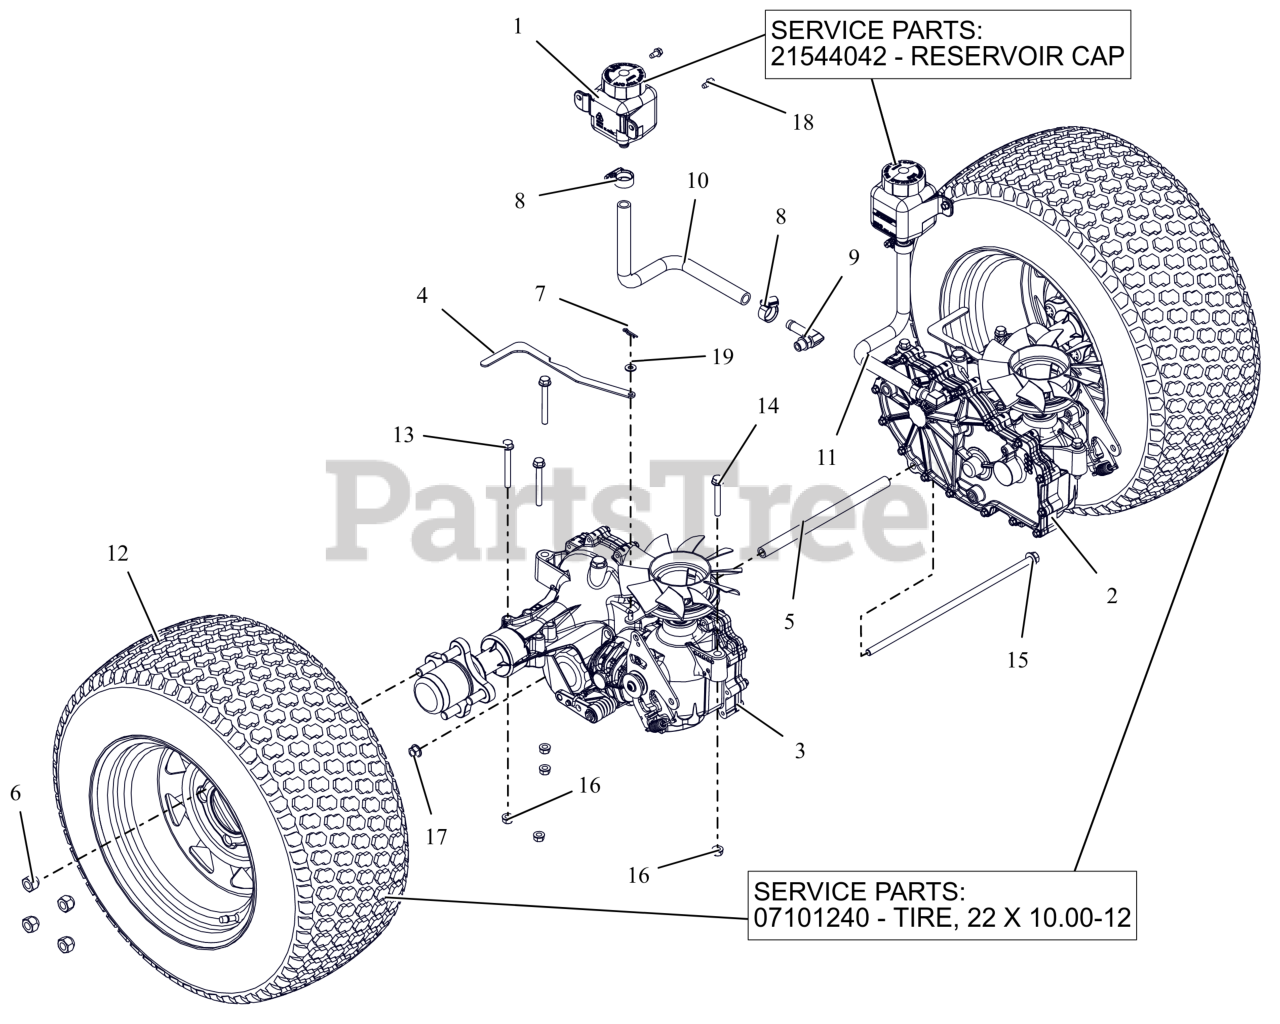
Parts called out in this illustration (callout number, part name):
1	TANK, EXPANSION
1	CAP, HYDRO RESERVOIR REPLAC.
2	TRANSAXLE, ZT3100 LH
3	TRANSAXLE, ZT3100 RH
4	BRKT, VALVE DUMP
5	SPCR,TRANS. .406IDX.63ODX9.95L
6	NUT, WHEEL .50-20 ZCC
7	PIN, HAIR #225 .072X1.09
8	CLAMP,.88 DIA. HOSE
9	FITTING, HYD (90 DEG)
10	HOSE, FORMED EXPANSION -HD RH
11	HOSE, FORMED EXPANSION -HD LH
12	ASM, WHL/TIRE 22X10.00-12 K500
12	TIRE, 22X10.00-12
13	BLT,HEX-FLG .31-18X2.75 G5 ZCC
14	BLT,HEX-FLG .31-18X2.25 G5 ZCC
15	BLT,HEX-FLG .38-16X13 G5 ZCC
16	NUT,LK-CTR-FLG .31-18 GF ZCC
17	NUT-LK-CTR-FLG .375-16 GF ZCC
18	SCR-TAP .25-20X.50 HWH ZCC
19	WSHR,FLT .281X.625X.065 ZCC
